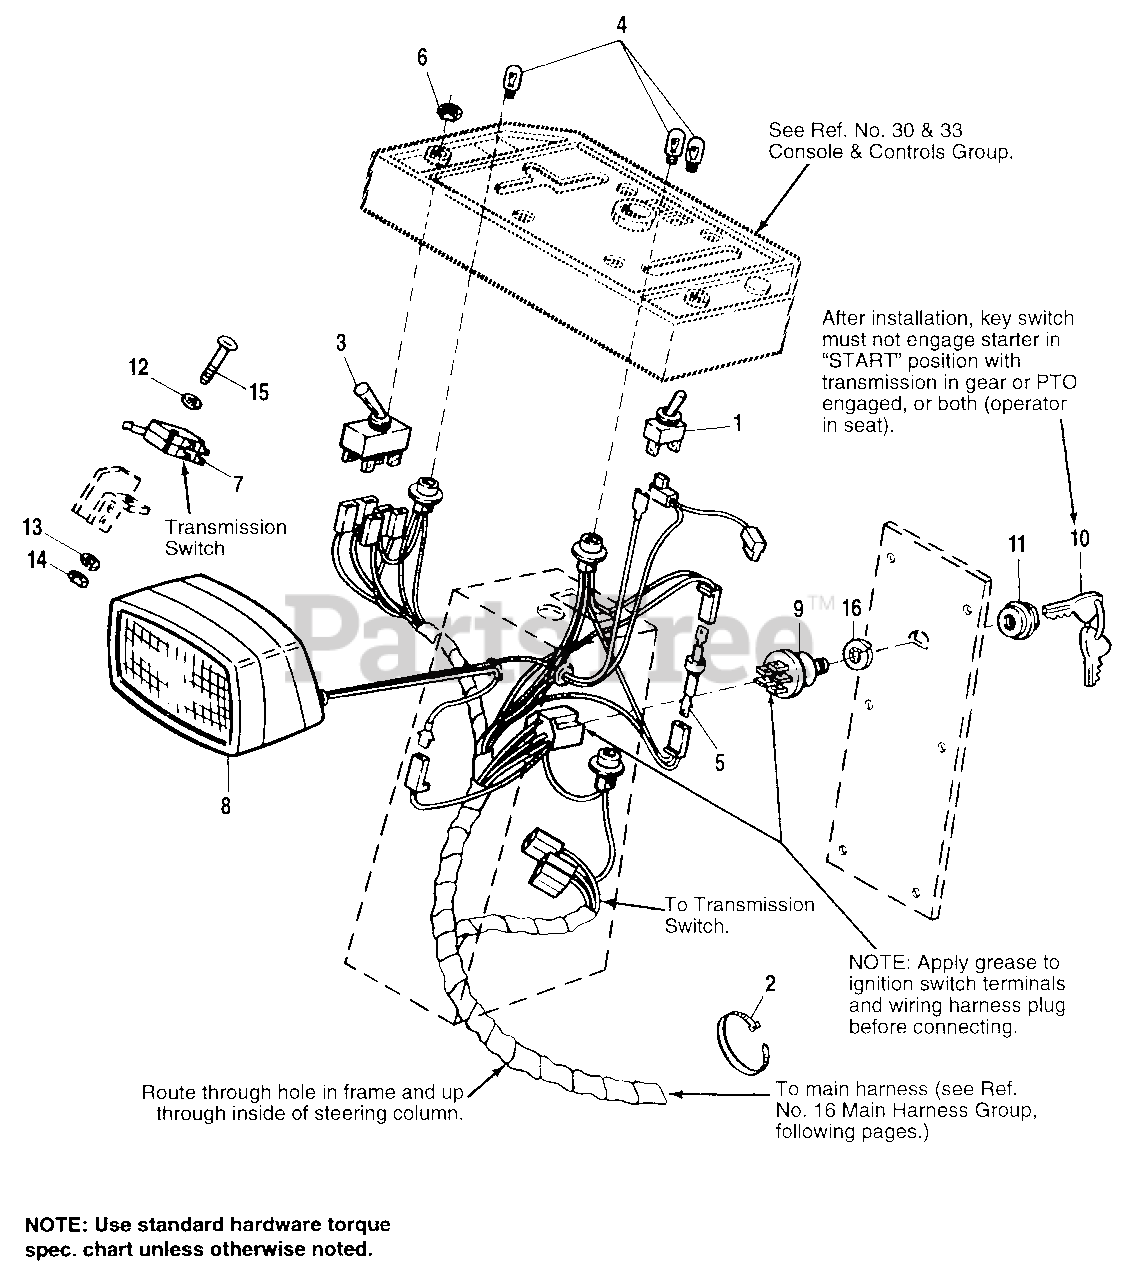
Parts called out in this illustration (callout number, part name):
1	SWITCH, Toggle
3	SWITCH ASSY. P.T.O. (Incl. Ref. No. 6)
4	LAMP, Indicator (Qty. 3 on 12.5 HP & 16 HP)
6	NUT, Special
7	MICRO SWITCH, Tandem
8	HEADLIGHT ASSY.
9	IGNITION SWITCH ASSY. (Incl. Ref. Nos. 10 & 11)
11	NUT, Adapter
12	WASHER, #6
13	LOCKWASHER, #5
14	NUT, Hex, #5-40
15	SCREW, Round Hd., #5-40 x 1-1/2
16	LOCKWASHER, Internal Tooth, 5/8
